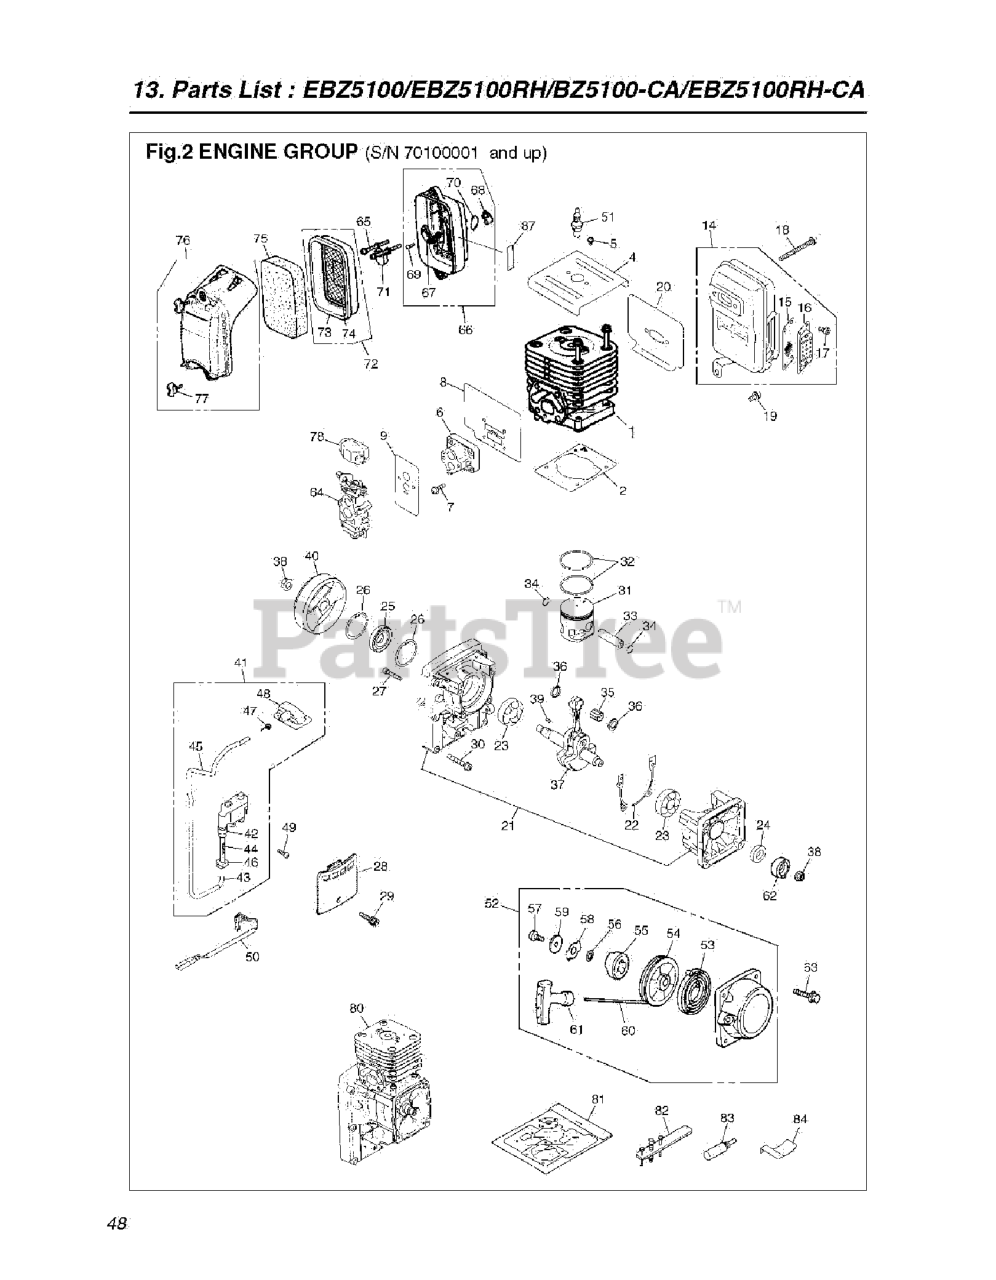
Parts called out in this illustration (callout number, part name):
1	CYLINDER***
3	BOLT
4	CYLINDER COVER
6	INSULATION
8	GASKET,INSULATOR
14	MUFFLER-A
15	SPARK ARRESTOR SCREEN
16	EXHAUST DUCT
20	GASKET
21	CRANKCASE
26	SNAP RING
30	BOLT
33	PIN
34	SNAP RING
37	CRANKSHAFT-C***
39	KEY
41	%COIL ASSY
42	CAP
45	RP TUBE-A
46	GROMMET
50	CORD-COMP
51	PLUG CMR7H
52	STARTER ASSY
54	STARTER PULLEY
55	STARTER PAWL
58	RETAINER
59	WASHER
60	CHORD
62	PULLEY
64	CARBURETOR***
66	CARBURETOR BODY
67	PLATE
69	SCREW
72	GASKET
74	SCREEN
75	AIR FILTER
76	COVER ASSY.
80	SHORT BLOCK
81	GASKET KIT
82	PULLER ASSY
87	LABEL,CHOKE
